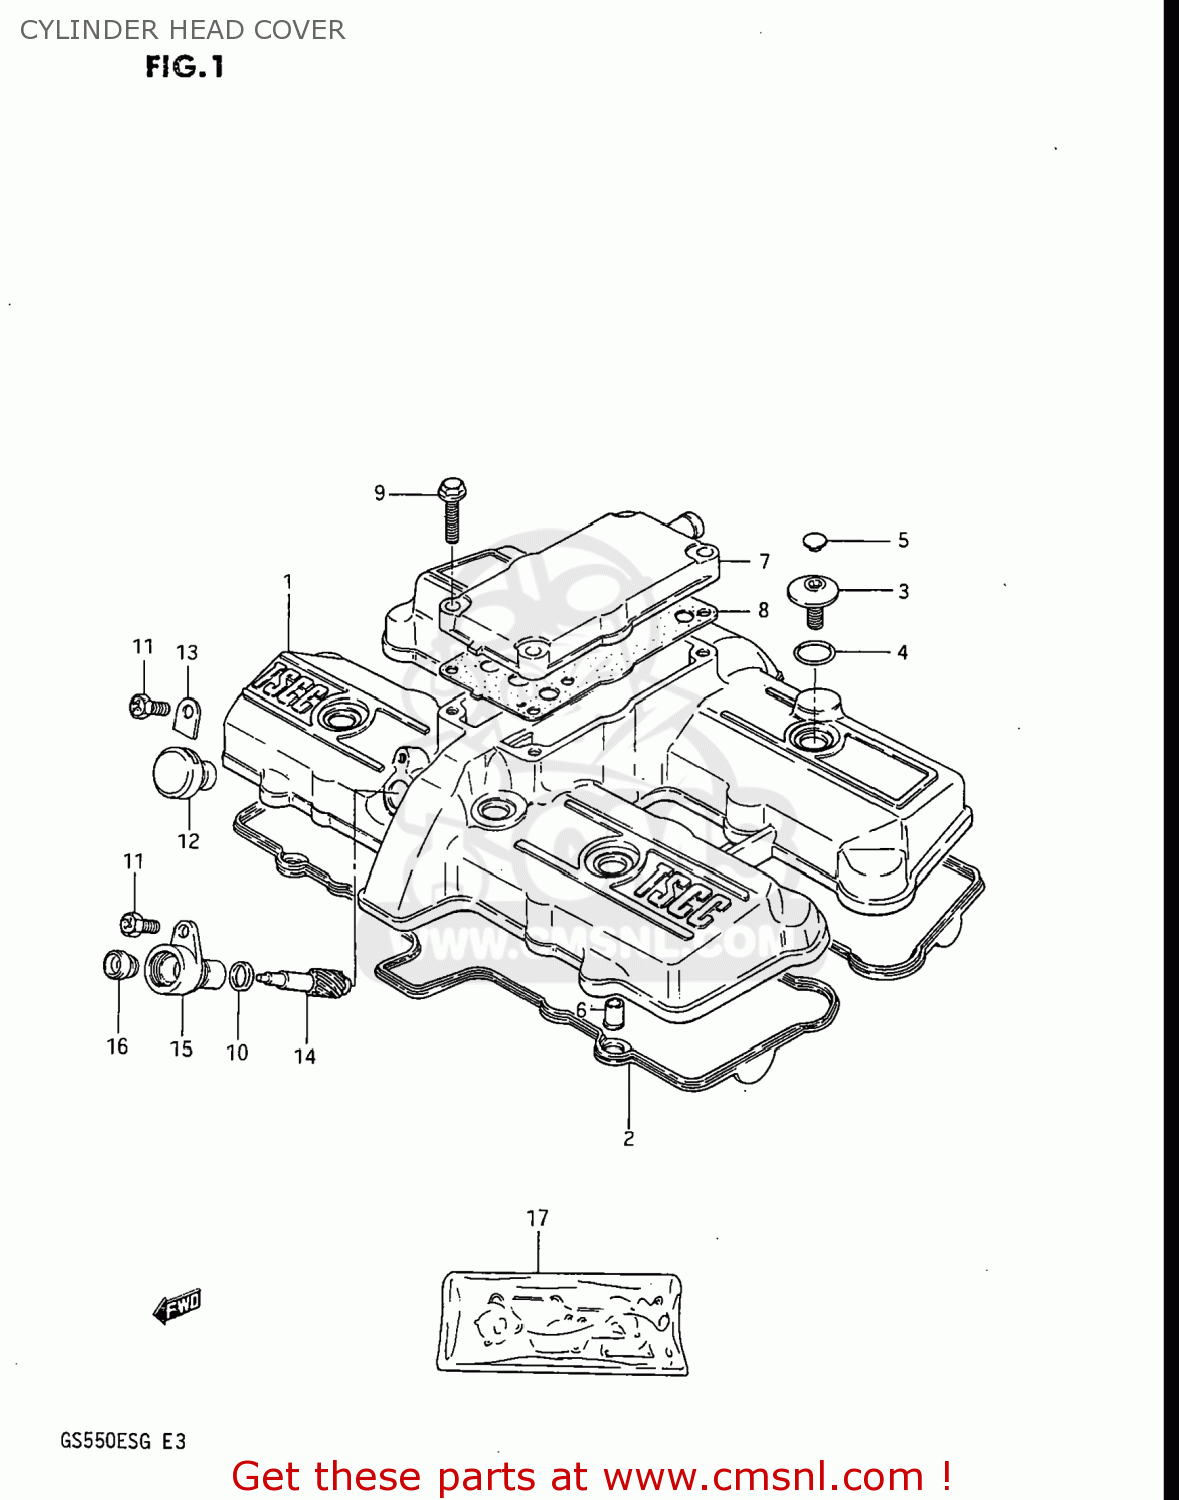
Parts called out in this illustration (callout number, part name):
1	COVER,CYLINDER HEAD
2	GASKET,CYL HEAD COVER (NAS)
3	BOLT(7X5.5)
4	O RING(D:1.9,ID:14.5)
5	CAP(OD:10)
6	PIN
7	COVER,BREATHER
8	GASKET (MCA)
9	BOLT
10	SEAL,TACHOMETER DRIVEN
11	SCREW(5X12)
12	PLUG,TACH GEAR SLEEVE HOLE
13	PLATE,TACH DRIVE GEAR SLEEVE
14	GEAR,TACHOMETER DRIVEN
15	SLEEVE,TACHOMETER DRIVE GEAR
16	SEAL,OIL(5X12X8)
17	GASKET SET (MCA)
